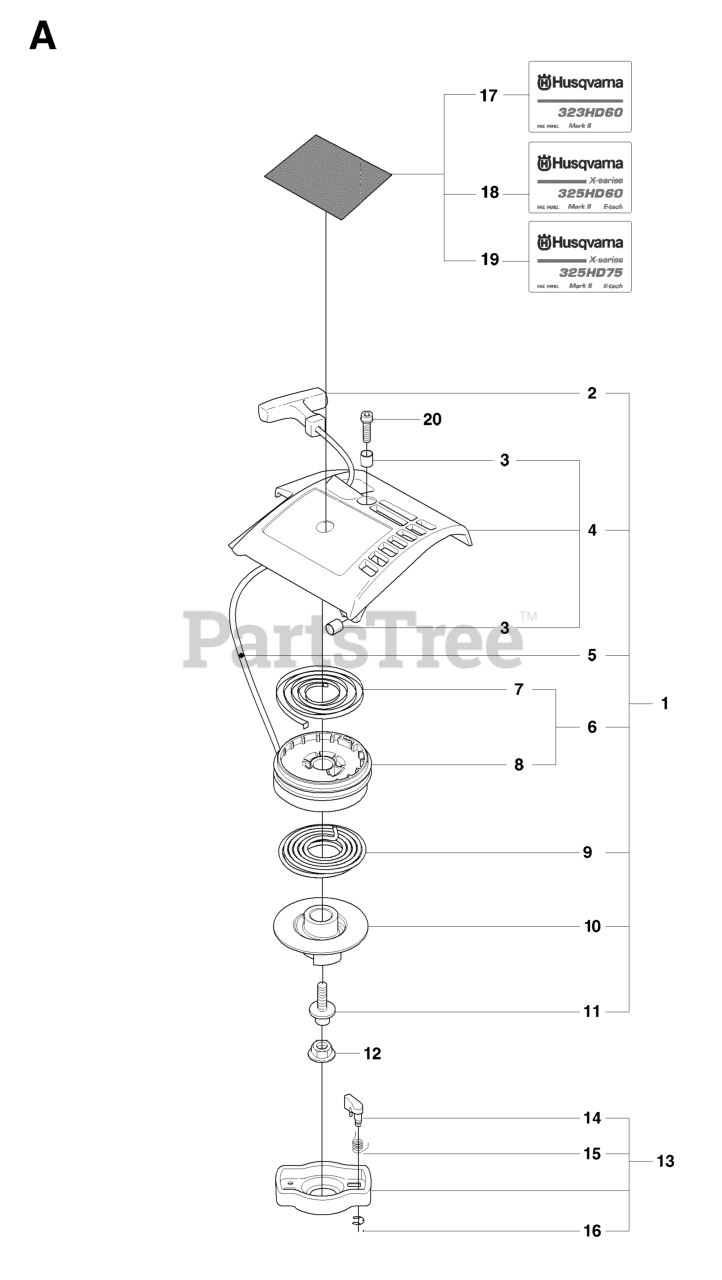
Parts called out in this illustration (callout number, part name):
1	RP STARTER ASSY
2	STARTER HANDLE
3	SPACING SLEEVE
4	STARTER HOUSING
5	STARTER ROPE
6	STARTER PULLEY
8	STARTER PULLEY
9	SPRING - DRIVER
10	DRIVER PULLEY
12	FLANGE NUT
13	PAWL ASSY COMPLETE
14	STARTER PAWL
